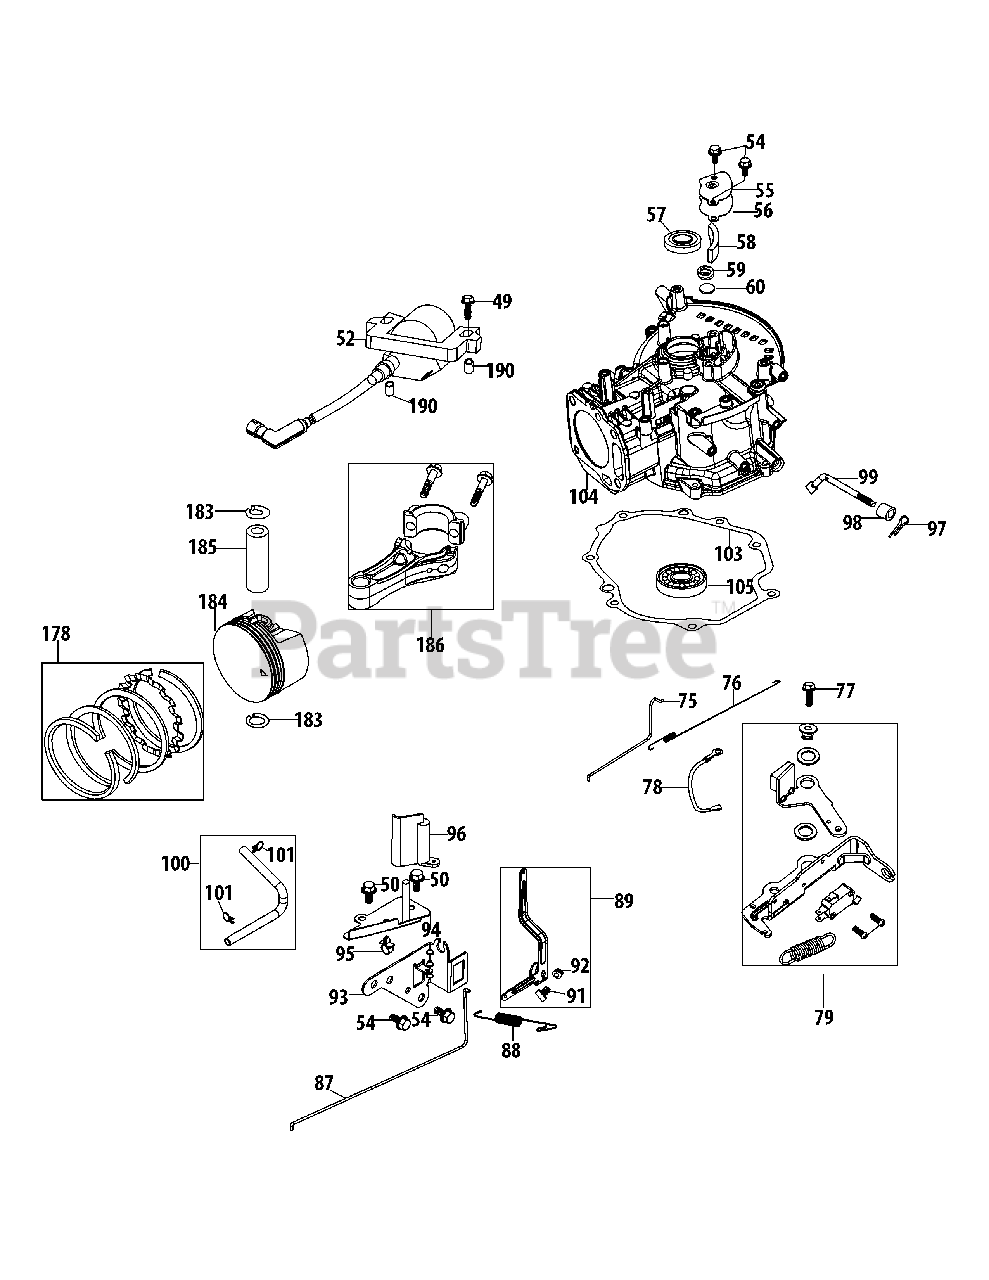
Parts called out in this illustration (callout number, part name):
49	Bolt M6X28 T/X/P Crankcase/Dp Stick
50	Bolt M6X12 Multi-Purpose
52	Ignition Coil Assembly
54	Bolt M6X14 Multi-Purpose
55	Breather Cover Plate
56	Breather Gasket
57	Upper Crankshaft Seal
58	Breather Screen
59	Breather Valve Spring
60	Breather Valve
75	Choke Linkage
76	Throttle Linkage Spring
77	Bolt M6×25 Ign/Brake/Cvr Plt
78	Grounding Wire
79	Brake Assembly
87	Throttle Linkage
88	Governor Spring
89	Governor Arm Assembly
91	Governor Arm Bolt
92	Governor Arm Nut M6
93	Component Bracket
94	Air Vane Bracket
95	Plastic Support Clamp
96	Air Vane
97	Governor Arm Shaft Cotter Pin
98	Governor Seal
99	Governor Arm Shaft
100	Breather Hose Assembly
101	Breather Hose Clamp
103	Crankcase Cover Gasket
104	Crankcase
104	(Mtd Srvc Kit) Short Block
105	Main Bearing
178	Piston Ring Set
183	Piston Pin Snap Ring
184	Piston
185	Piston Pin
186	Connecting Rod Assembly
190	Ignition Coil Spacer
